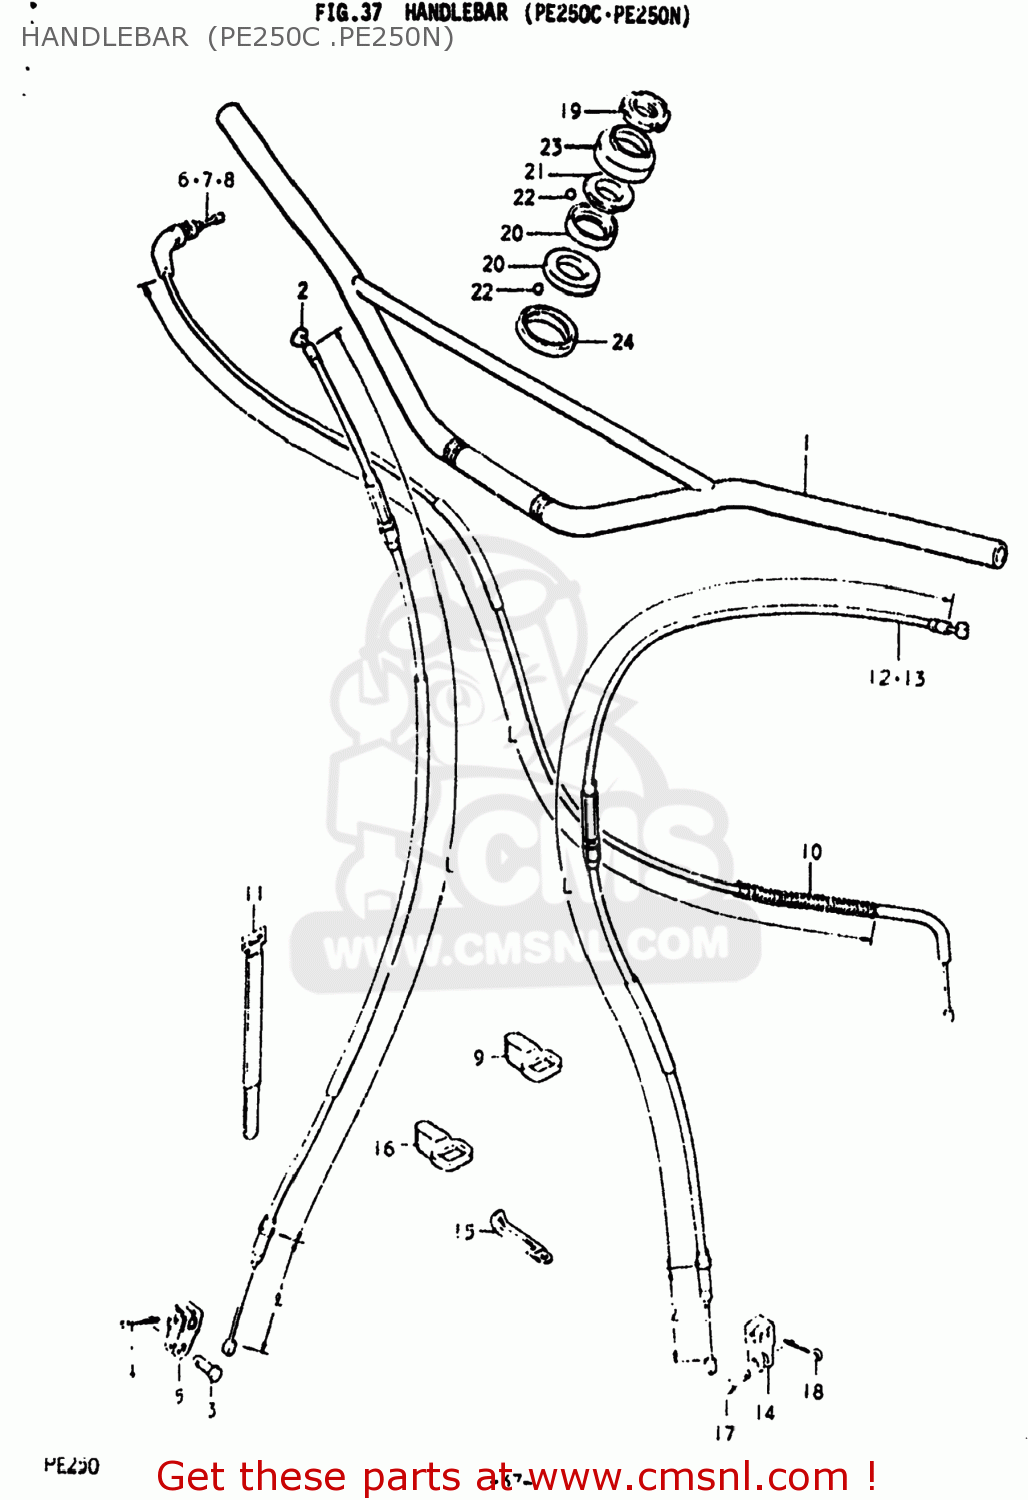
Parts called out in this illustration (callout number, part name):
1	HANDLEBAR
2	CABLE,FR BRAKE
3	PIN(L:13.5)
4	PIN
5	BRAKE CABLE HOOK
6	CABLE ASSEMBLY,THROTTLE
7	CABLE ASSY,THROTTLE
8	CABLE ASSEMBLY,THROTTLE
9	GUIDE,CABLE
10	PROTECTOR,CABLE
11	CLAMP
12	CABLE ASSEMBLY,CLUTCH
13	CABLE ASSEMBLY,CLUTCH
14	HOOK,CLUTCH CABLE
15	CLAMP
16	GUIDE,CABLE
17	PIN(L:13)
18	PIN
19	NUT,STEERING STEM(25X44X10)
20	LACE,STEERING INNER LWR
21	LACE,STEERING OUTER UPR
22	BALL
23	DUST SEAL,STEERING,UPPER
